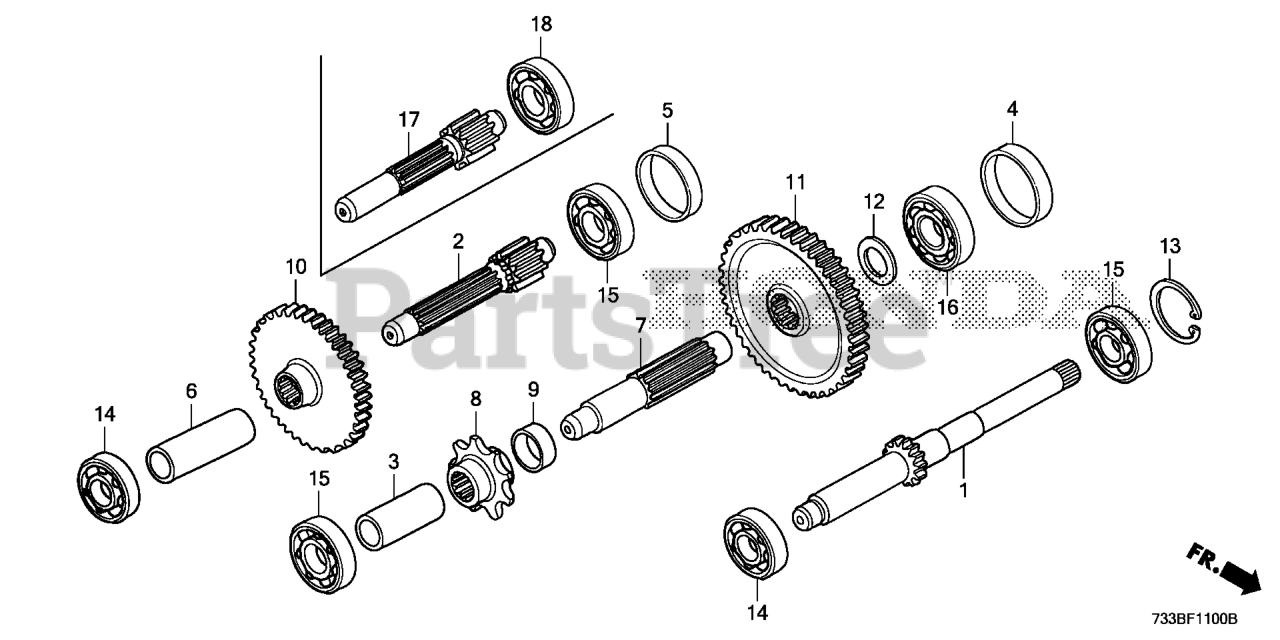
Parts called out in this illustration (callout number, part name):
1	SHAFT, INPUT (18T)
3	COLLAR (22) (2X30)
4	COLLAR, DISTANCE
5	COLLAR, DISTANCE
6	COLLAR A, COUNTERSHAFT
7	SHAFT, FINAL
8	SPROCKET, DRIVE (9T)
9	COLLAR, FINAL SHAFT
10	GEAR, COUNTERSHAFT FIRST (50T)
11	GEAR, FINAL (58T)
12	WASHER (17MM)
13	CIRCLIP (INNER) (35MM)
14	BEARING, RADIAL BALL (6002)
15	BEARING, RADIAL BALL (6202)
16	BEARING, RADIAL BALL (6203)
17	COUNTERSHAFT (13T)
18	BEARING, RADIAL BALL (6302)
